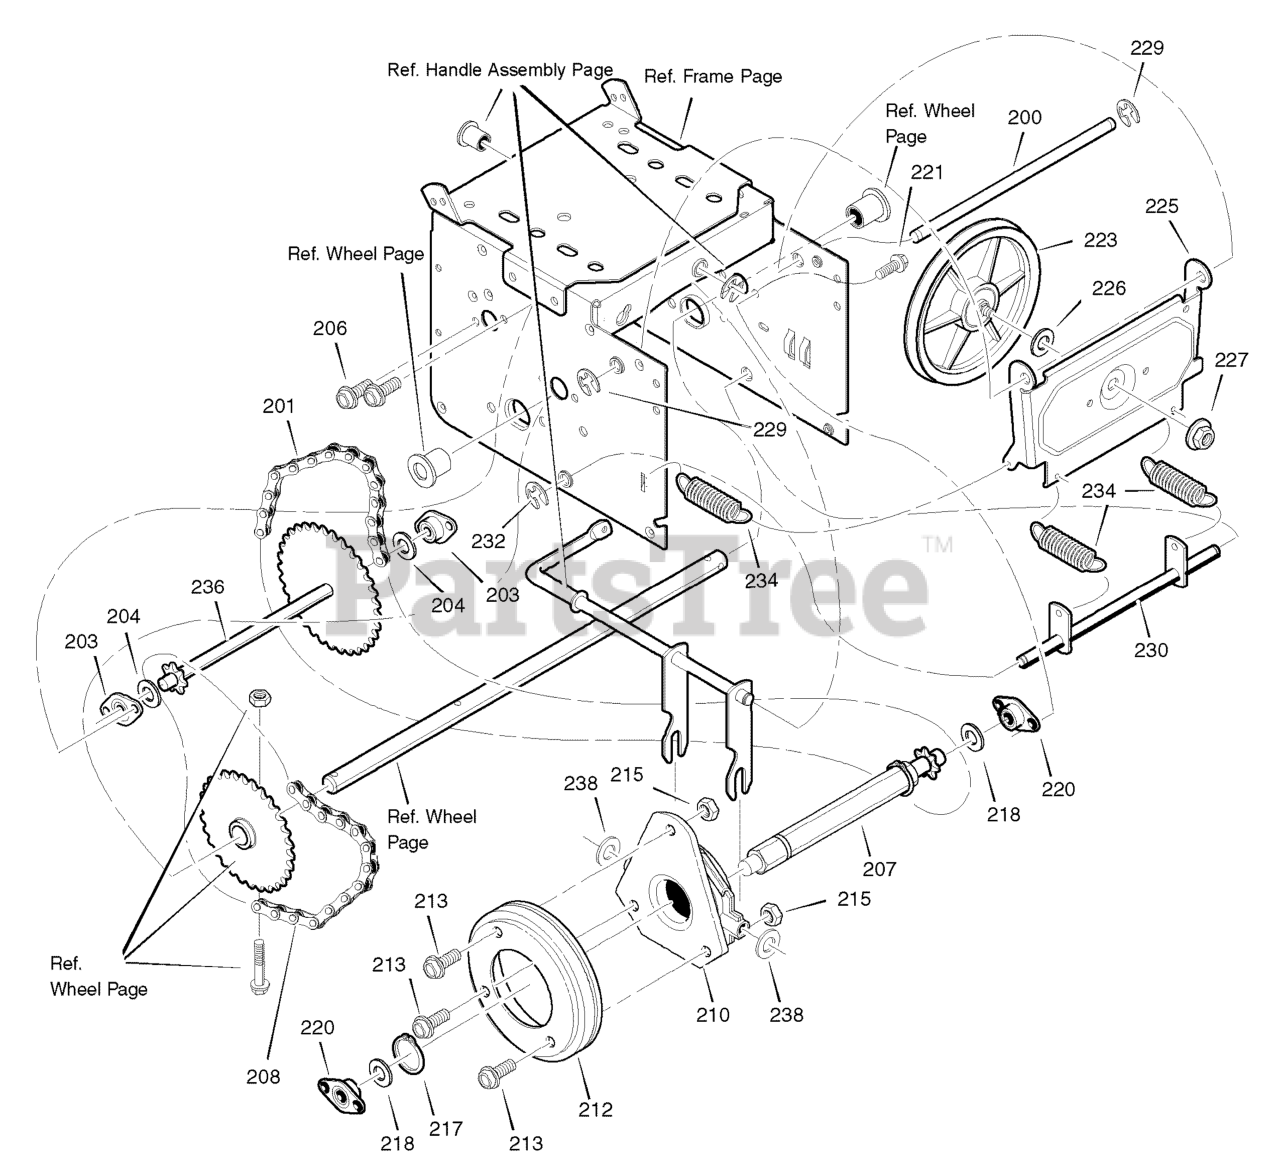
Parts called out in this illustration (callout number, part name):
200	LF AXLE, SWING PLATE YZ
201	CHAIN, ROLLER #420 X 19.00
203	BEARING AND RETAINER, ASSEMBLY
206	SCREW, TAP 5/16-18 X 1/2
207	HEX SHAFT ASSEMBLY
208	CHAIN, ROLLER #420 X 18.00 LG
210	BEARING, TRUNION CLUTCH R
212	WHEEL, FRICTION DISC
215	NUT, KEPS HEX 1/4-20
217	RING, RETEXT
220	BEARING AND RETAINER, ASSEMBLY
221	SCREW, TAP 5/16-18 x 1/2
223	FRICTION PULLY
225	LF PLATE, SWINGING YZ
226	SPACER, FRICTION PULLEY
227	NUT, FLANGE LOCK 3/8-24
229	RETAINER, RING
230	LF ASSEMBLY, SPRING LINK YZ
232	RETAINER, RING
234	SPRING, EXTENSION
236	SPROCKET, WELD, INTERMED 33T/7
238	WASHER, FLAT
